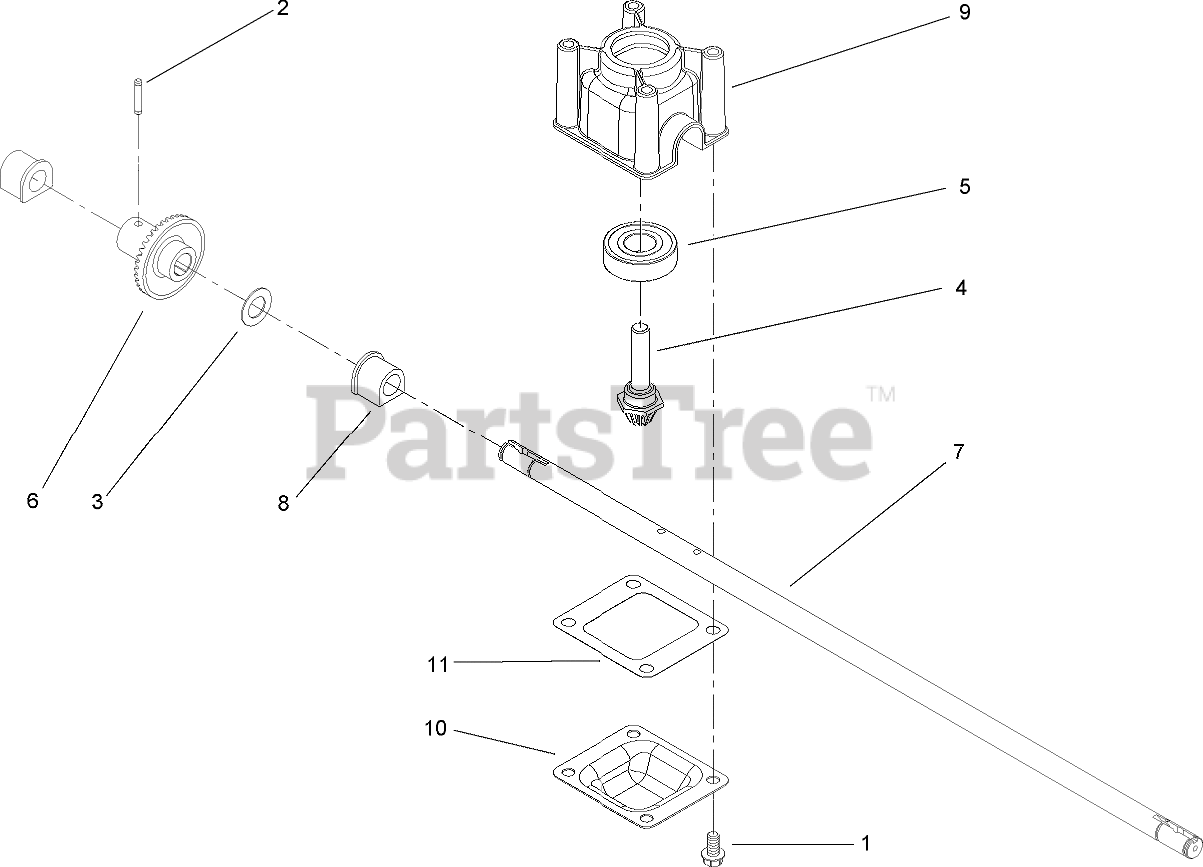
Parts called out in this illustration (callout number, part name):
1	SCREW-HWH
2	PIN-GROOVE
3	WASHER-PLAIN
4	PINION
5	BEARING-BALL
6	Gear-Bevel, 37t
7	Shaft-Output
8	Bushing-Shaft, Output
9	Gearcase-Upper
10	Cover-Gearcase
11	Gasket-Gearcase
